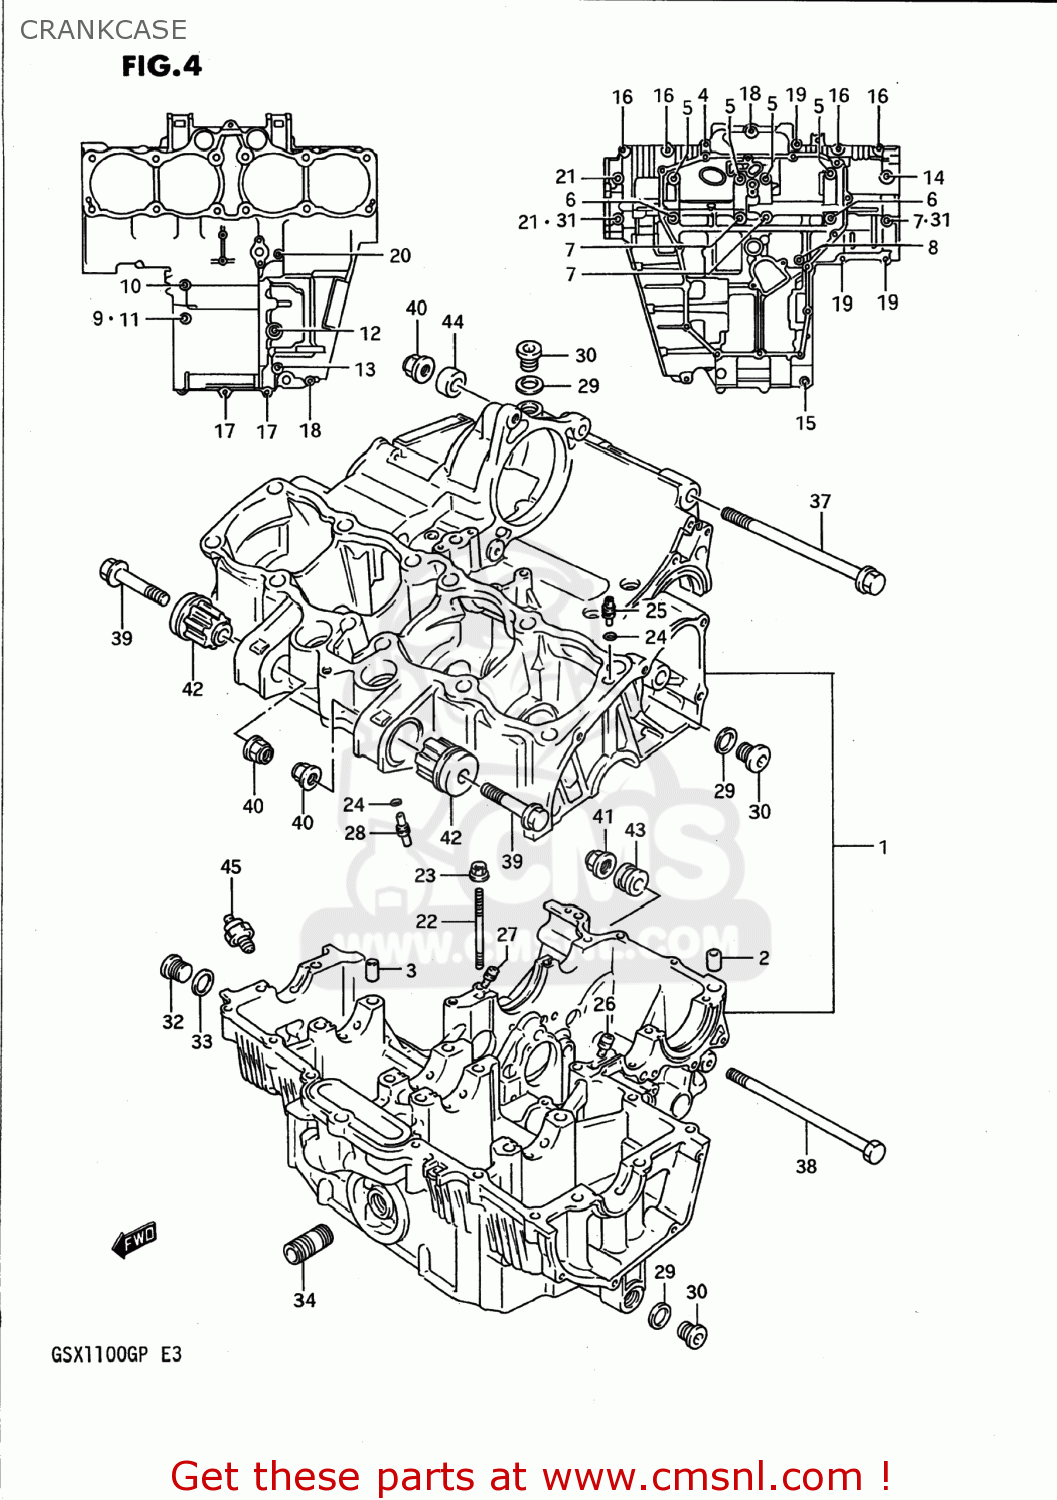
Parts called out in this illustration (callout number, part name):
1	CRANKCASE SET
2	PIN(10.4X13X22)
3	PIN (11X20)(SUS)
4	BOLT 6X100
5	BOLT 8X135
6	BOLT(8X145)
7	BOLT
8	BOLT(6X120)
9	GASKET(8.2X14X1) (NAS)
10	BOLT ,8X50
11	BOLT, REAR RH
12	BOLT
13	BOLT
14	BOLT(8X85)
15	BOLT
16	BOLT 6X35
17	BOLT
18	BOLT (6X60)
19	BOLT
20	BOLT (6X80)
21	BOLT(8X95)
22	STUD BOLT
23	NUT
24	O RING(D:1.2,ID:4)
25	JET,AIR
26	JET
27	JET(140)
28	JET
29	GASKET(16X22X2) (NAS)
30	PLUG
31	GASKET(8.5X17X2.3) (NAS)
32	PLUG,14X12
33	GASKET(14X19.2X2) (NAS)
34	UNION,OIL STAND
35	BEARING,CRANK THRUST(GREEN)
36	BEARING,CRANK THRUST(RED)
37	BOLT L:165
38	BOLT 12X151
39	BOLT
40	NUT (10MM)
41	NUT 12MM
42	BUSH,ENGINE MOUNTING
43	SPACER,ENGINE MOUNT
44	SPACER,ENGINE MOUNT
45	SWITCH ASSEMBLY
